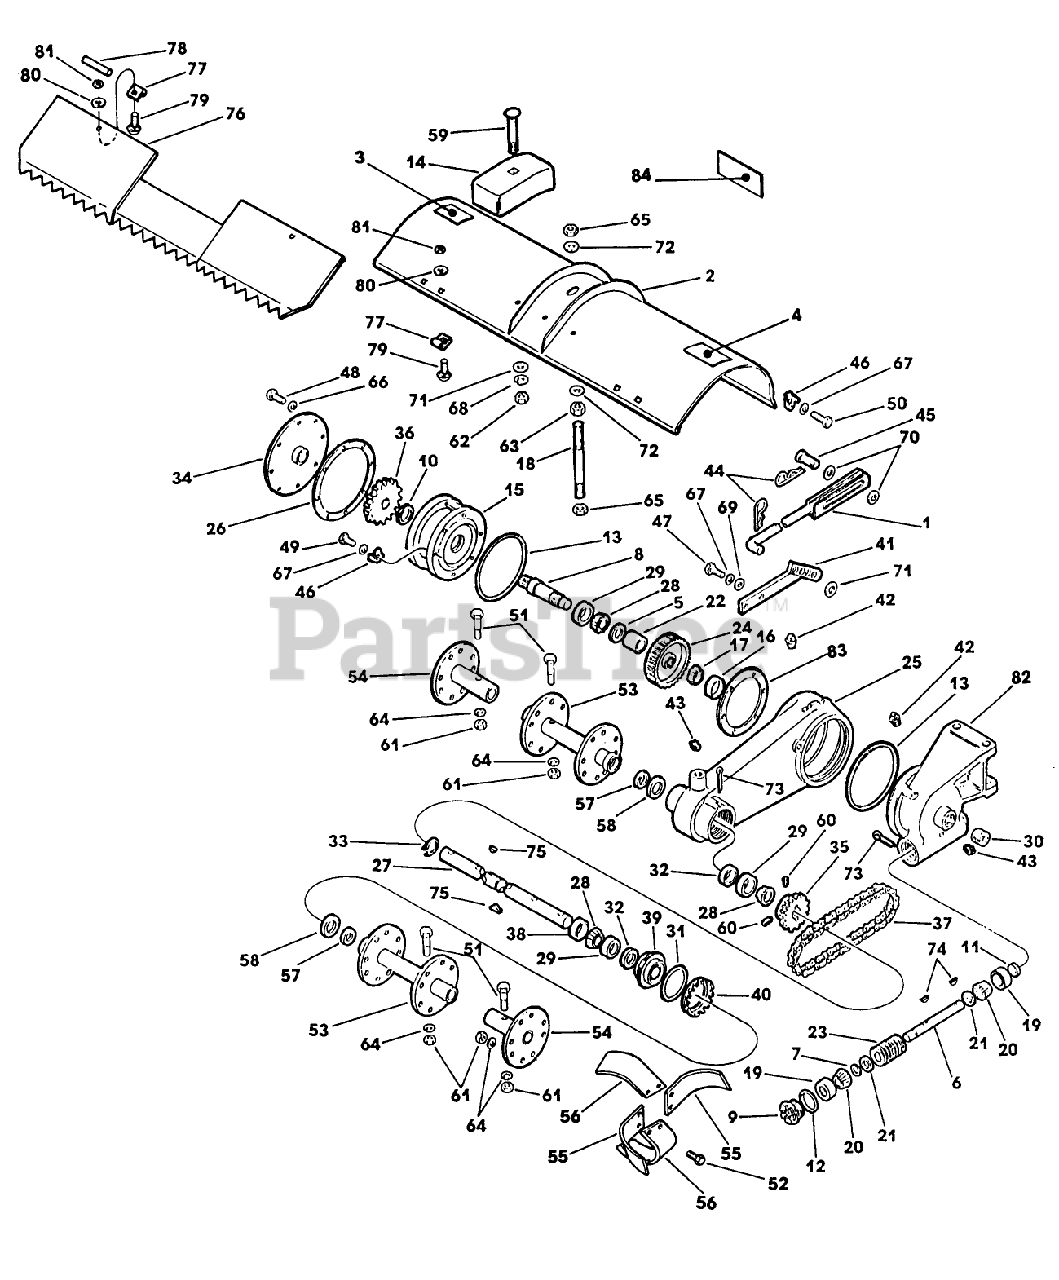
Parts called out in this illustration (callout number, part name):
5	ROD - LEVEL - RH *F
6	SHAFT WORM
8	SHAFT & SLEEVE AY
10	OIL SEAL - 1.500
15	PLATE
18	STUD-TINE SHIELD
21	SPACER - WORM
22	SPACER-WORM WHEEL
23	WORM
24	WORM WHEEL
26	GASKET
27	SHAFT
37	CHAIN - 60#
38	SPACER
44	PIN - SPRING CLIP
48	SCREW-HH
52	SCREW-CAP HEX HEAD
54	OUTER TINE HUB AY *B
57	FELT SEAL - INNER
58	SEAL - FELT
60	SET SCREW
61	HEX NUT
63	NUT - HEX JAM
67	WASHER
69	WASHER
75	KEY-HYPRO
81	NUT SS
83	GASKET
